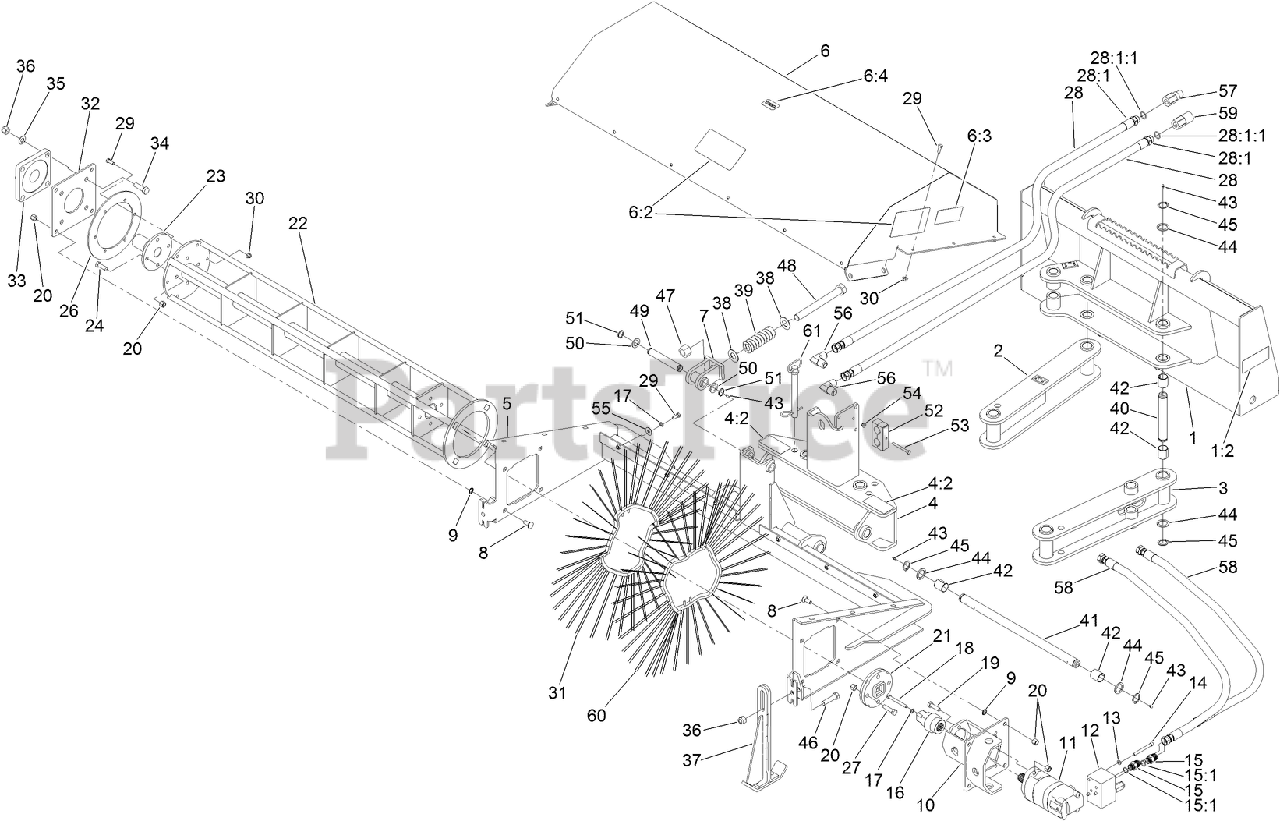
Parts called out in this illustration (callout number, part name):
1	FRAME ASM
1:2	DECAL-WARNING
2	LINK-FOLLOWER
3	LINK-DRIVER
4	KNUCKLE ASM
4:2	DECAL-WARNING, PINCH POINT
5	FRAME-HOOD
6	HOOD ASM
6:2	DECAL-DANGER
6:3	DECAL-WARNING
6:4	DECAL
7	RETAINER-SPRING
8	SCREW-CARR
9	NUT-PUSH
10	MOUNT-MOTOR
11	HYDRAULIC MOTOR ASM
12	MANIFOLD
13	SCREW-HH
15	FITTING-STRAIGHT
15:1	O-RING
16	ADAPTER-MOTOR
17	WASHER-LOCK
18	SCREW-HH
19	SCREW-HH
20	NUT-LOCK, NI
21	FLANGE-DRIVE
22	CORE-BROOM
23	PLATE-DRUM
24	SCREW-HH
26	PLATE-BRUSH
27	SCREW-HH
28	HOSE ASM
28:1	FITTING-STRAIGHT
28:1:1	O-RING
29	SCREW-HH
30	NUT-HF, NI
31	WAFER-WIRE STRAND
32	PLATE-MOUNT, BEARING
33	BEARING-FLANGED
34	SCREW-HH
35	WASHER-FLAT
36	NUT-LOCK, NI
37	STAND-BROOM
38	WASHER
39	SPRING-COMPRESSION
40	PIN-PIVOT
41	PIN-HINGE
42	BUSHING
43	FITTING-ZERK
44	WASHER-STEERING
45	RING-RETAINING, EXTERNAL
46	SCREW-HH
49	PIN-HINGE
50	SPACER-HARDENED
51	RING-RETAINING
52	CLAMP-HOSE
53	SCREW-HH
54	NUT-HF, NI
55	WASHER,FLAT,0.406IDX1.25OD,ST/ST 18
56	FITTING-ELBOW
57	FITTING-HYD
58	HOSE-HYD
59	FITTING-HYD
60	WAFER-POLY
61	PIN-HITCH
